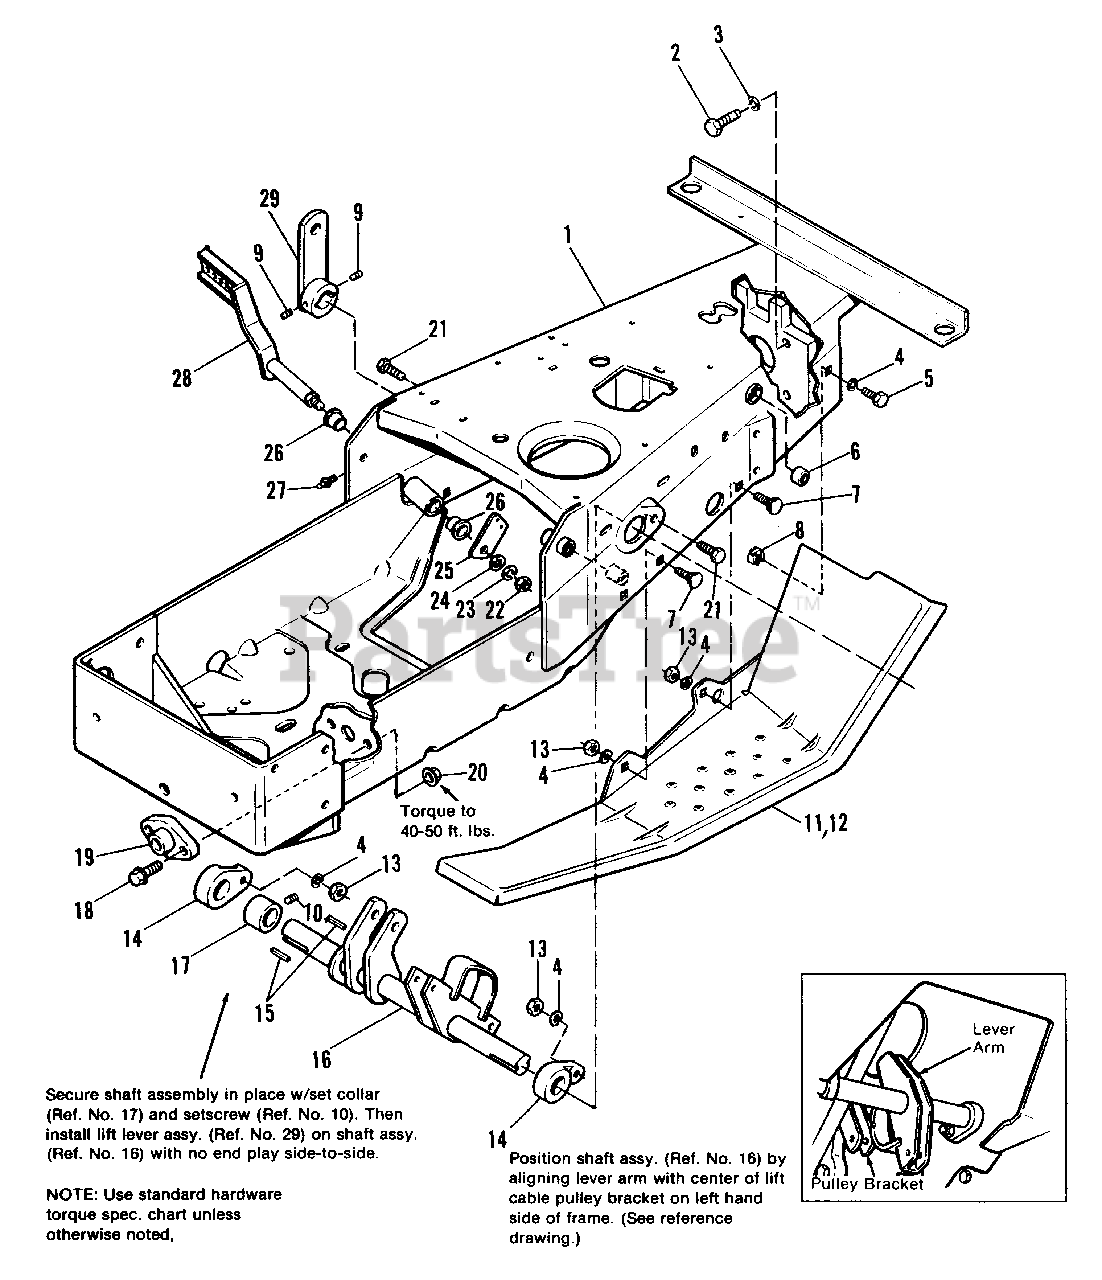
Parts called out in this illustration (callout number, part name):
1	FRAME ASSY., w/Bushings (7112 only)
1	FRAME ASSY., w/Bushings (7117 only)
2	CAPSCREW, Hex Hd., 7/16-14 x 1-1/2
3	LOCKWASHER, 7/16
4	LOCKWASHERS, 5/16
5	CAPSCREW, Hex Hd., 5/16-18 x 3/4
7	BOLT, Carriage, 5/16-18 x 3/4
8	NUT, Speed, 5/16-18
9	SETSCREW, 5/16-18 x 1/4
10	SETSCREW, 5/16-18 x 3/8
11	FOOTREST, LH
12	FOOTREST, RH
13	NUT, Hex, Full, 5/16-18
14	BEARING, Lift Lever
16	SHAFT ASSY., Lift
16	SHAFT ASSY., Lift (7112 only)
17	COLLAR, Set
18	SCREW, Hex, Whiz, Flange, 3/8-16 x 1-1/4
19	BEARING, Pivot
20	LOCKNUT, Hex, Flange, 3/8-16
21	CAPSCREW, Hex Hd., 5/16-18 x 1-3/4
22	NUT, Hex, Full, 3/8-16
23	LOCKWASHER, 3/8
24	WASHER, Plain, 3/8
25	ARM, Foot Pedal
27	FITTING, Grease
28	PEDAL ASSY., Foot
29	LEVER ASSY., RH
